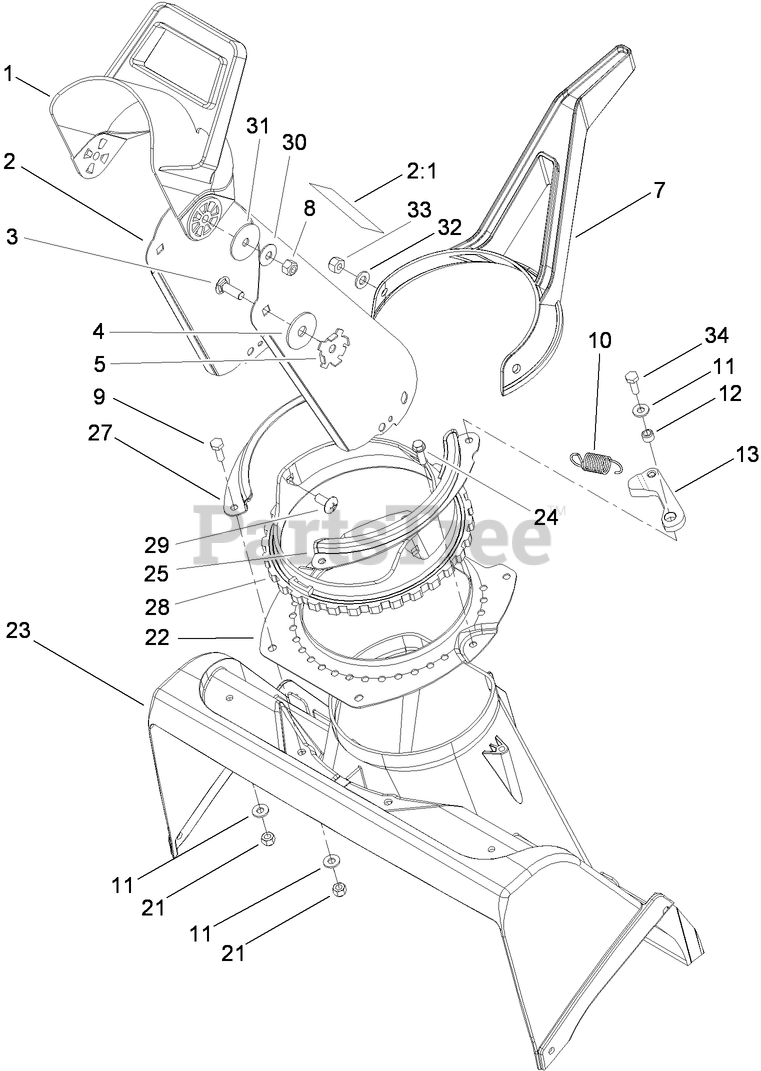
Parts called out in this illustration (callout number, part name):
1	CHUTE-DEFLECTOR
2	CHUTE ASM
2:1	DECAL-DANGER
3	SCREW-CARR
4	WASHER-RUBBER
5	PLATE-FRICTION
7	HANDLE-CONTROL, CHUTE
8	NUT-LOCK, NI
9	SCREW-HH
10	SPRING-EXTENSION
11	WASHER-FLAT
12	SPACER-BLADE, ROTOR
13	DETENT
21	NUT-LOCK, NI
22	RING-SUPPORT, CHUTE
23	HOUSING-ROTOR, UPPER
24	SCREW-HWH
25	RETAINER-CHUTE, LH
27	RETAINER-CHUTE, RH
28	RING-CHUTE
29	SCREW-PTH
30	WASHER-BELLEVILLE
31	WASHER-FLAT
32	WASHER-FLAT
33	NUT-LOCK, NI
34	SCREW-HH
